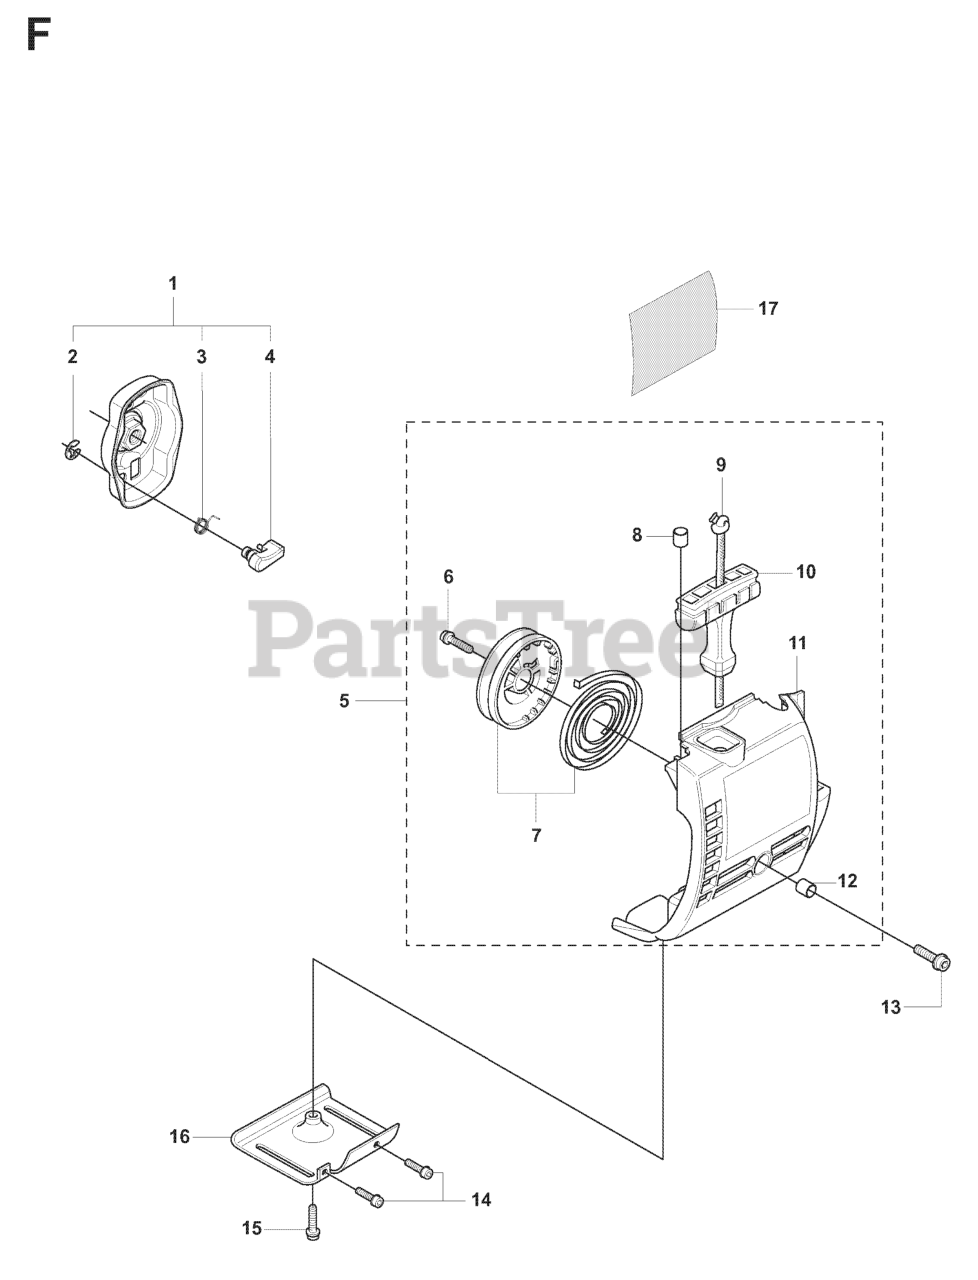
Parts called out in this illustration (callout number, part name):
1	STARTER PAWL BRIDGE
4	STARTER PAWL
5	STARTER ASSY
7	STARTER PULLEY ASSY.
8	SPACING SLEEVE
9	STARTER ROPE
10	STARTER HANDLE
11	RP STARTER HOUSING
12	SPACING SLEEVE
